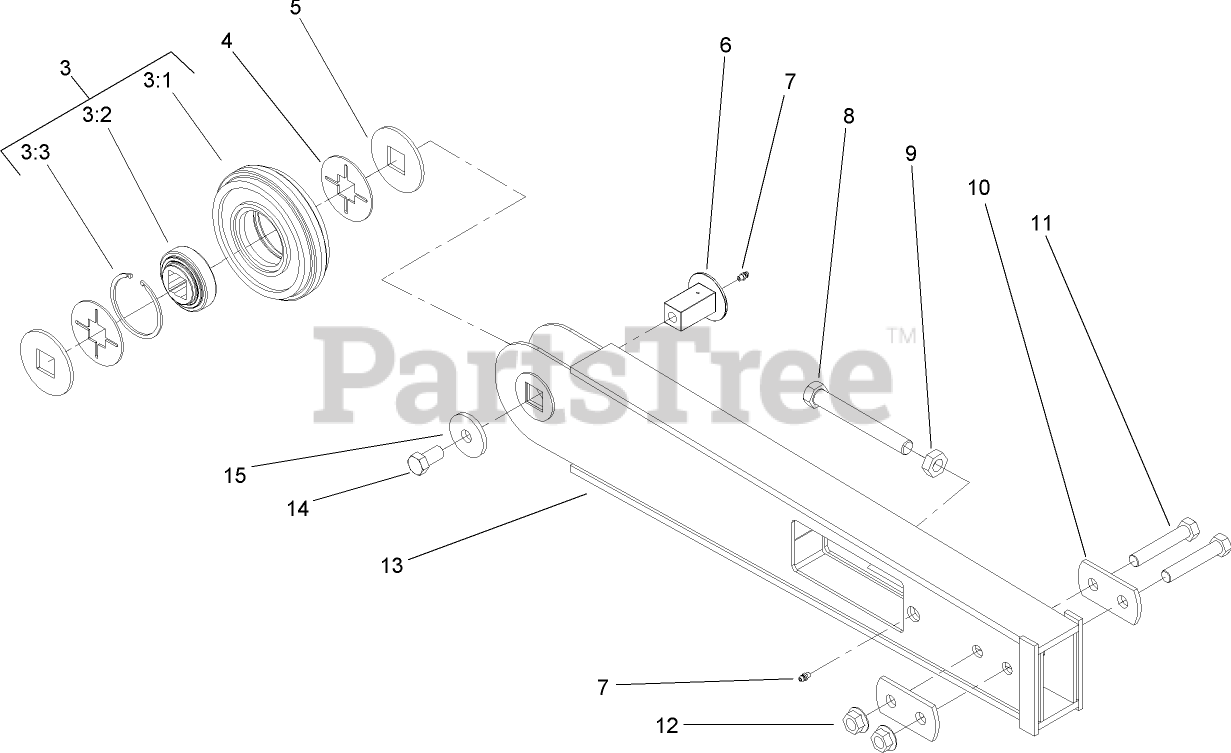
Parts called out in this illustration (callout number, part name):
3	TRENCHER ROLLER ASM
3:1	ROLLER-NOSE
3:2	BEARING
3:3	RING-RETAINING
4	SPACER-ROLLER
5	CAP-ROLLER
6	AXLE-ROLLER
7	FITTING-GREASE
8	BOLT-ADJUSTMENT
9	NUT-JAM
10	PLATE-SUPPORT
11	SCREW-HH
12	NUT-FLANGE
13	BOOM ASM
14	SCREW-HH
15	WASHER
